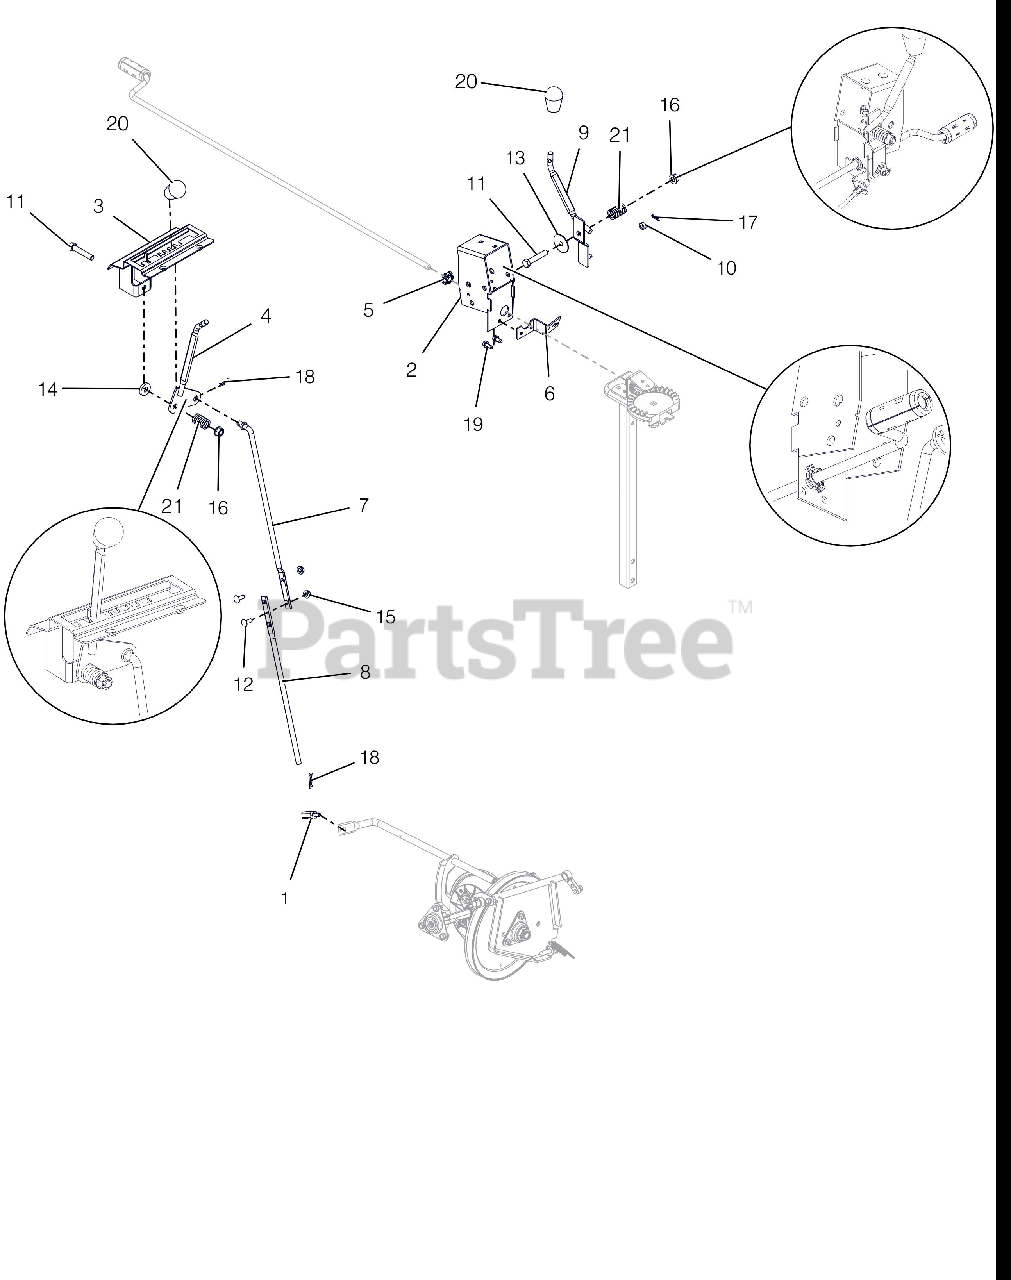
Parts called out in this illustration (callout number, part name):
1	PIVOT,SHIFT ROD .375-16(TRUNN)
2	WELDMENT, BRACKET INTERLOCK
3	WELDMENT, DETENT PLATE-COMPACT
4	LEVER, CONTROL-SHIFT(WELDMENT)
5	CRANK BUSHING, NYLON CHUTE BK
6	ANCHOR, DEFLECTOR CABLE
7	ROD, SHIFT - UPPER
8	ROD, SHIFT - LOWER(SMALL DASH)
9	WELDMENT,SM DASH DEFL CONTROL
10	BSHG-SLV .265X.500X.219
11	@BLT-HEX .38-16X2.00 GR5 YWZC
12	@BLT-RDHDSQNK .25-20X.75 G5YZ
13	WSHR-FL-STL .380X1.50X.062 YWZ
14	WSHR-FL-STL .406X1.00X.188 YWZ
15	@NUT-LK-CTR-FLG .25-20 YWZC
16	@NUT-LK-TOP-FLG .38-16 YWZC
17	PIN-HAIR INT .06X.18X.77
18	PIN-HAIR INT .08X.18X1.18 YWZC
19	SCR-TAP .25-20X.50 HWH TR YWZ
20	KNOB,SOFT TEARDROP,PUSH-ON BLK
21	SG-COMP .125X.781X1.250
